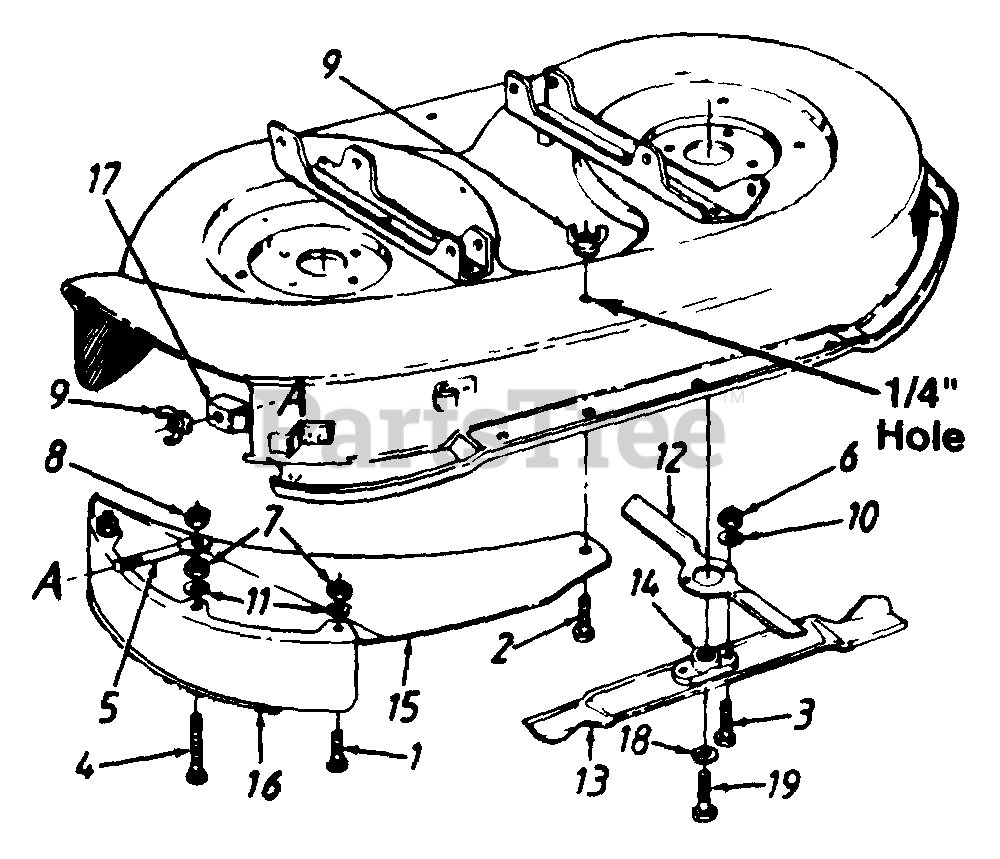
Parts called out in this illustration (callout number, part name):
1	Carriage Bolt 1/4-20 x .62" Lg.
2	Hex Bolt 1/4-20 x .62" Lg.
3	Hex Bolt 7/16-20 x 1.25" Lg. (Gr. 5)
4	Carriage Bolt 1/4-20 x 1" Lg.
5	Retaining Bolt
6	Hex Nut 7/16-20 Thd.
7	Hex Nut 1/4-20 Thd.
8	Hex L-Nut 1/4-20 Thd.
9	Wing Nut
10	L-Wash. 7/16" I.D.
11	L-Wash. 1/4" l.D.
12	Mulching Blade 12.5"
13	Mulching Blade 19,38"
14	Blade Adapter
18	L-Wash. 3/8" I.D.
19	Hex Bolt 3/8-24 x 1" L. Gr. 8
